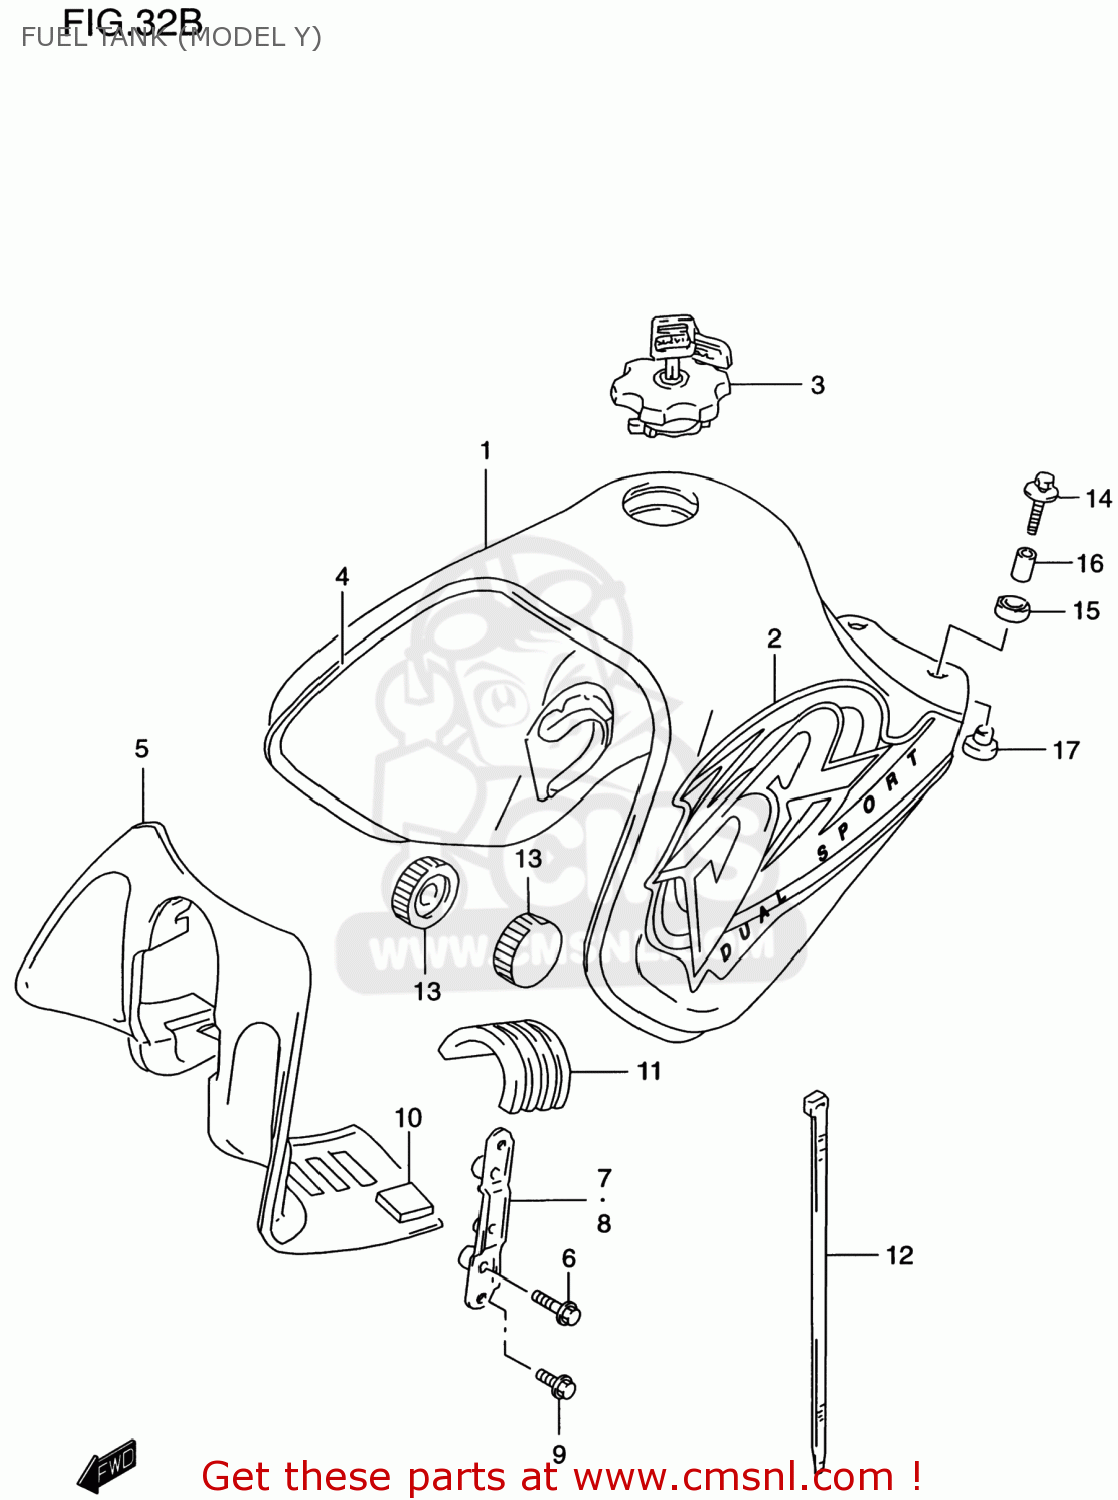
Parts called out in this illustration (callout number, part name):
1	TANK ASSEMBLY,FUEL
2	TAPE SET,FUEL TANK
3	CAP SET,FUEL TANK
4	MOLDING,FUEL TANK
5	COVER,FUEL TANK FR
6	BOLT 6X14
7	BRACKET,FUEL TANK COVER,R
8	BRACKET,FUEL TANK COVER,L
9	BOLT
10	CUSHION,HEADLAMP COVER
11	CUSHION,FUEL TANK UPR
12	CLAMP(L:250)
13	CUSHION,FUEL TANK FR
14	BOLT(6X30)
15	CUSHION
16	SPACER(6.5X9X18)
17	CUSHION
